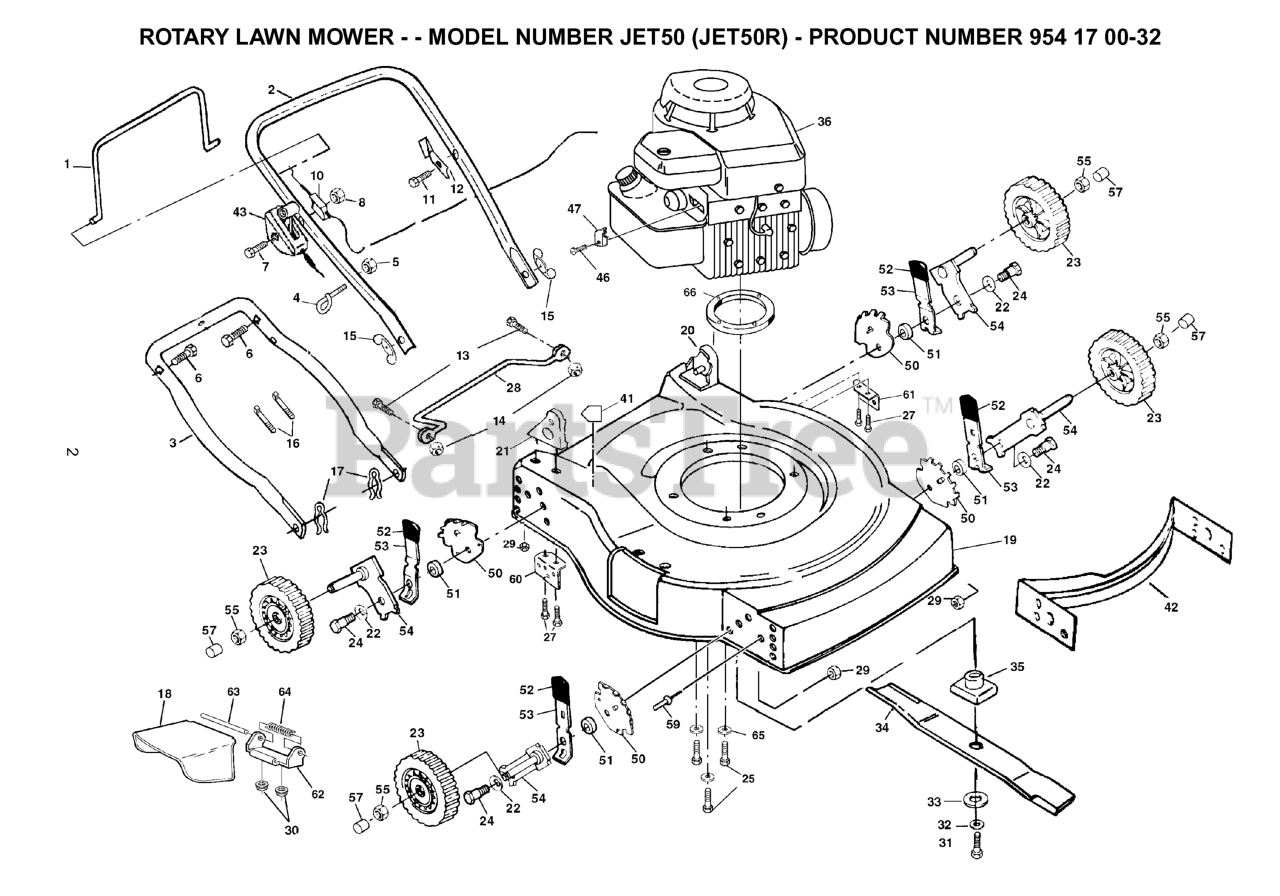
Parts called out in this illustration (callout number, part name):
1	CONTROL BAR
2	UPPER HANDLE
3	HANDLE
4	ROPE, GUIDE
5	NUT
6	HANDLE BOLT
7	SCREW 1/4-20 X 2.12
8	NUT
10	CABLE.MZR.51.RT.SP./PU.
12	BRACKET UPSTOP
13	REPL BY 817 02 10-08
15	NUT WING PM
16	TIE GUIDE
17	HAIRPIN COTTER
20	HANDLE BRACKET ASM. LH
21	HANDLE BRACKET ASM. RH
22	WASHER.BELLEVILLE (3 2 LB)
23	WHEEL
24	BOLT
27	SCREW.5/16-18X3/4
29	LOCKNUT PM
30	NUT
31	SCREW, HEX HD 3/8-24 X 1-3/8
32	LOCKWASHER
33	WASHER,HARDEN
34	20" Blade
35	BLADE ADAPTOR
41	DECAL.INTERNATIONL.CUTFINGER
46	SCREW.HEX.HEAD.WASHER.10-16
47	CABLE CLAMP(ENGINE)
50	WHEEL ADJUST BRACKET
51	RP SPACER HT ADJ
53	SELECTOR SPRING
54	AXLE, REAR
55	HEX FLANGE LOCKNT
59	RIVET BLIND
60	Bracket Support (Right)
61	BRKT SUPPORT(L)
62	BRACKET PM
63	ROD.HINGE.COMBI-C
